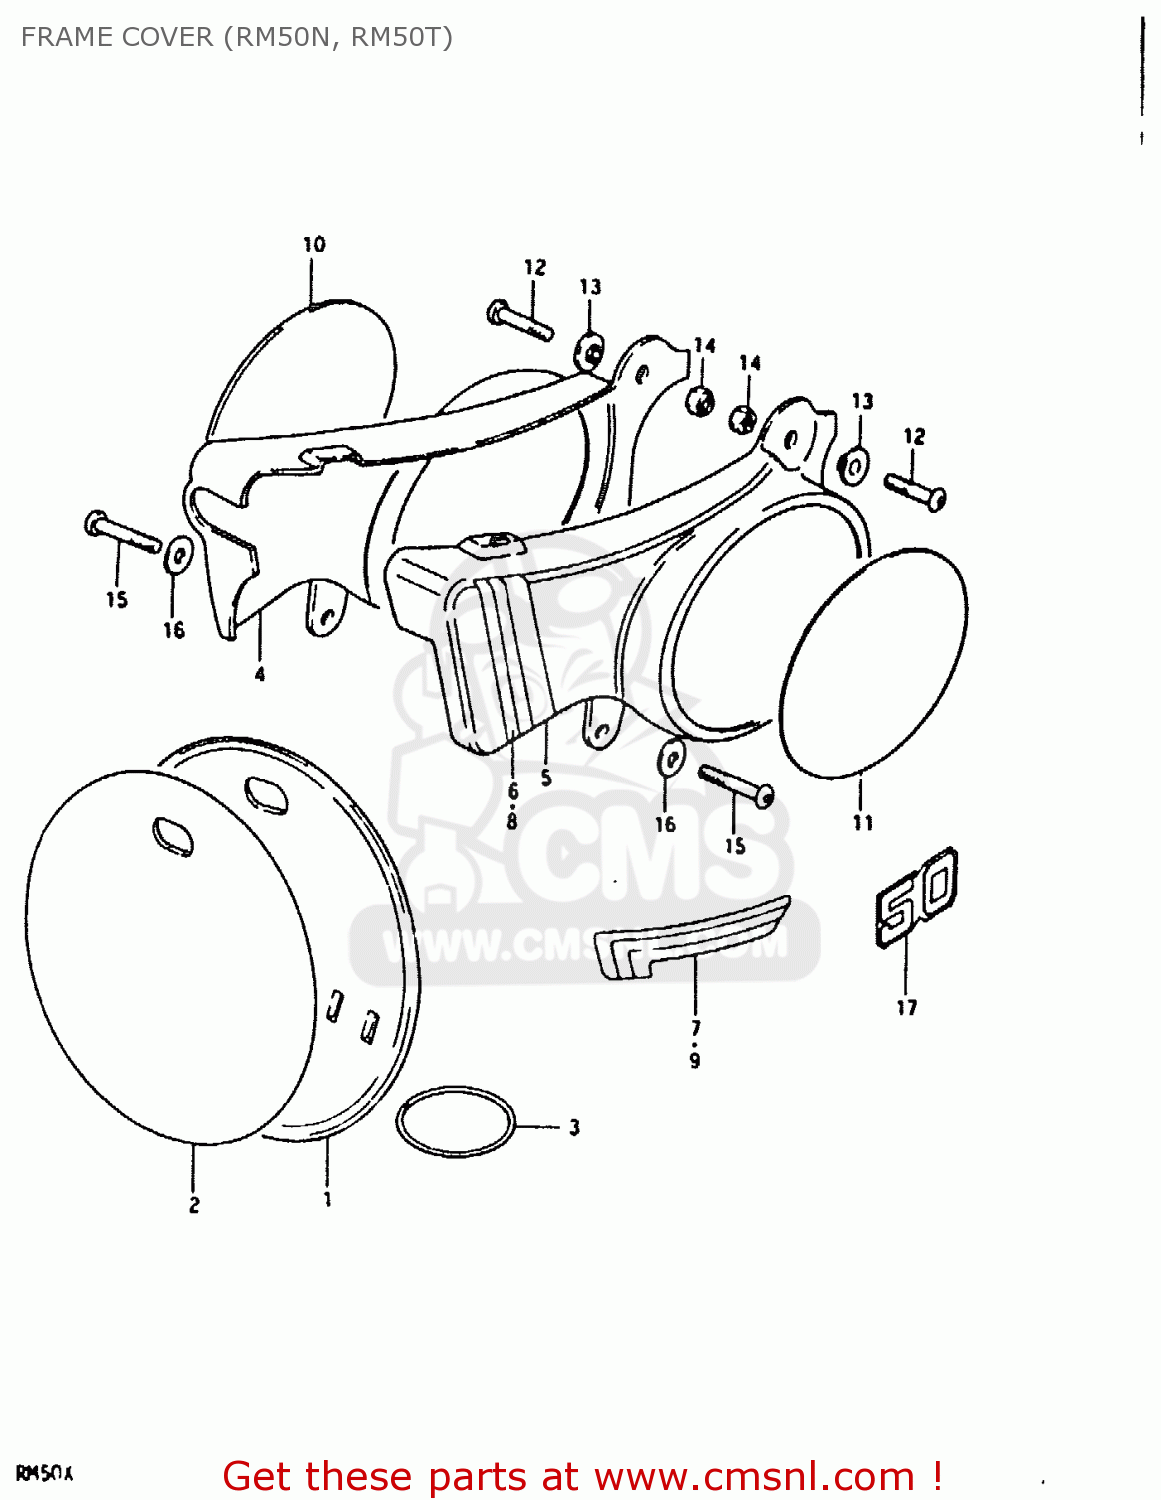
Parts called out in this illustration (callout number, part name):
1	PLATE,NUMBER,FRONT
2	EMBLEM,FRONT NUMBER PLATE
3	O-RING
4	COVER,FRAME,RIGHT
5	COVER,FRAME,LEFT
6	TAPE,FRAME COVER
7	TAPE,FRAME COVER
8	TAPE, STRIPING LH
9	TAPE,FRAME COVER
10	TAPE,FRAME COVER NUMBER PLATE
11	LABEL,FRAME COVER
12	SCREW
13	WASHER
14	NUT
15	SCREW
16	WASHER
17	EMBLEM
